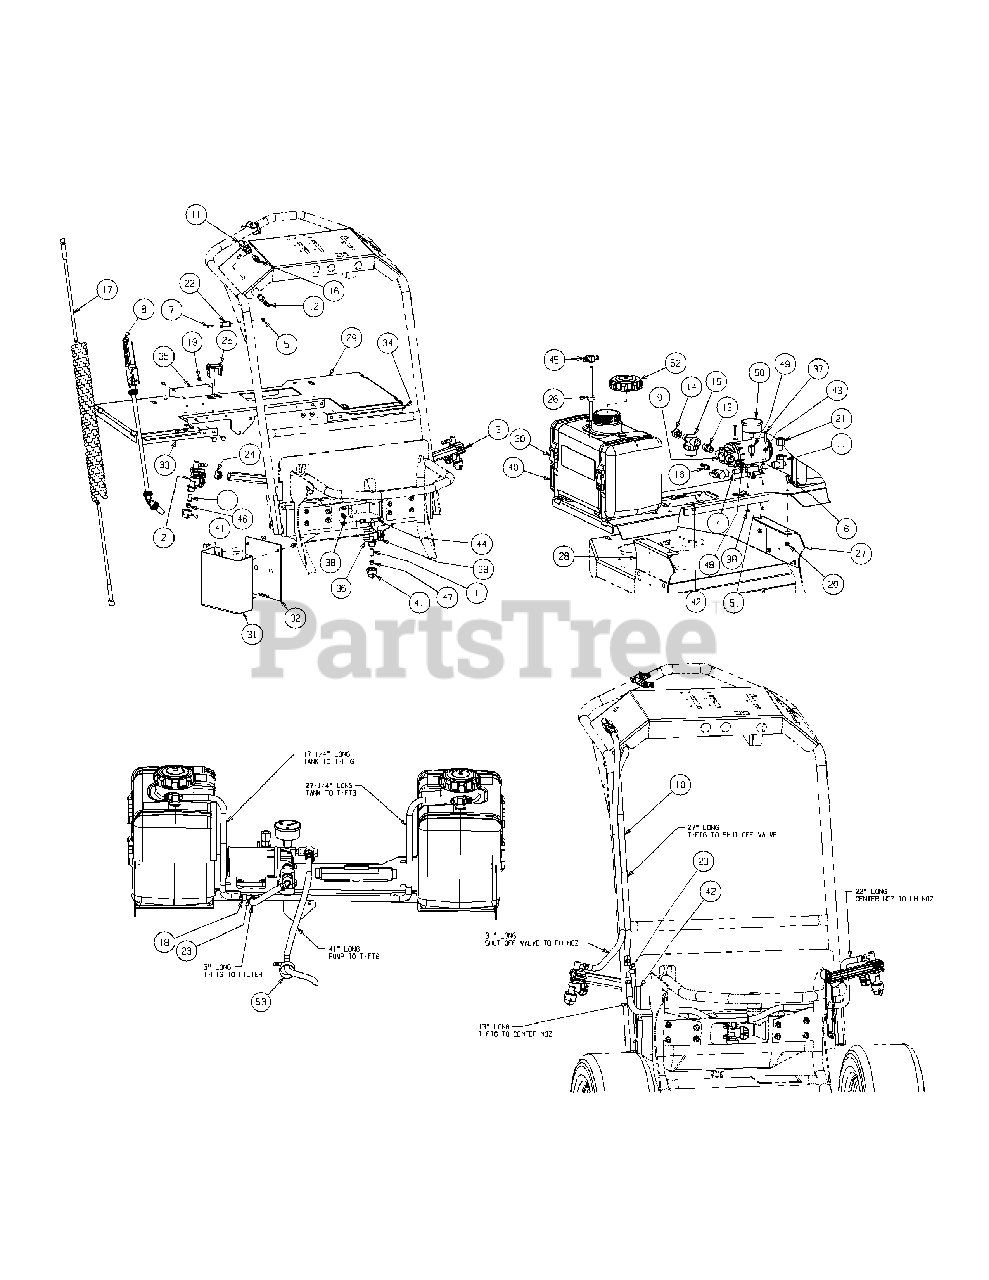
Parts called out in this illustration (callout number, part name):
1	Strainer Screen, 50 Mesh, SS
2	Single Dry Boom Nozzle Body
3	Nozzle Body Clamp, 1" SQ.
4	1/4" Brass Nipple
5	Lock Nut, Nylon Insert, #10-32
6	Carriage Bolt, 1/4-20 x .75
7	Phillips Head Screw, 10-32
8	Spray Wand
9	Pump, Flojet 25 GL
10	Hose, 3/8 x 17.20ft - 300psi
11	Valve, 1/4 90 Deg. Female
12	Fitting, 1/4 MPT x 3/8
13	Fitting, 8-145-00, Shurflo
14	Fitting, 8-060-01, Shurflo
15	Filter, 170-061-00, Shurflo
16	Fitting, 1/4 MET x 3/8 Barb, nylon
17	Hose Assembly, 25ft blue
18	Hose Clamp, 1/4-5/8, SS
19	Self Tapping Screw, #10-24 x 0.500
20	Nut, #10-24, Hex Flange Lock
21	Adaptor, 3/8 FNPT, 1/4 MNPT
23	Tee Fitting, 3/8 Multi Barb
24	Plastic Plug
26	Fuel Tank Grommet
27	Sprayer Plate Adaptor Bracket, RH
28	Sprayer Plate Adaptor Bracket, LH
33	Support Bracket, RH
36	U-Bolt, #10-24
37	HHCS, #10-24 x 1.25
38	Nut, #10-24, Hex Flange Nylon
39	Nozzle Body, Center
40	Tank, 5 Gallon
41	Cap, Nozzle Body
42	Battery Edge Trim
43	Washer, .194 x .62 OD x .063
44	Tee Fitting, 1/4 NPTF x 3/8
45	Fitting, Sprayer Pickup
46	Fitting, Off Center Spray Tip
46	Optional Fitting, Off Center Brass Spray Tip
47	Fitting, Flat Spray Tip
47	Optional Fitting, Flat Yellow Spray Tip
47	Optional Fitting, Flat Red Spray Tip
47	Optional Fitting, Flat Silver Spray Tip
48	Fitting, 3/8 NPTF x 1/4 NPTF
49	Fitting, 1/4 NPTF x 1/8 NPTM
50	Pressure Gauge, 0-100 psi
51	Tee, 3/8 NPTF, Brass
53	Reel Return Line Sleeve, 1.59, 15"LG
